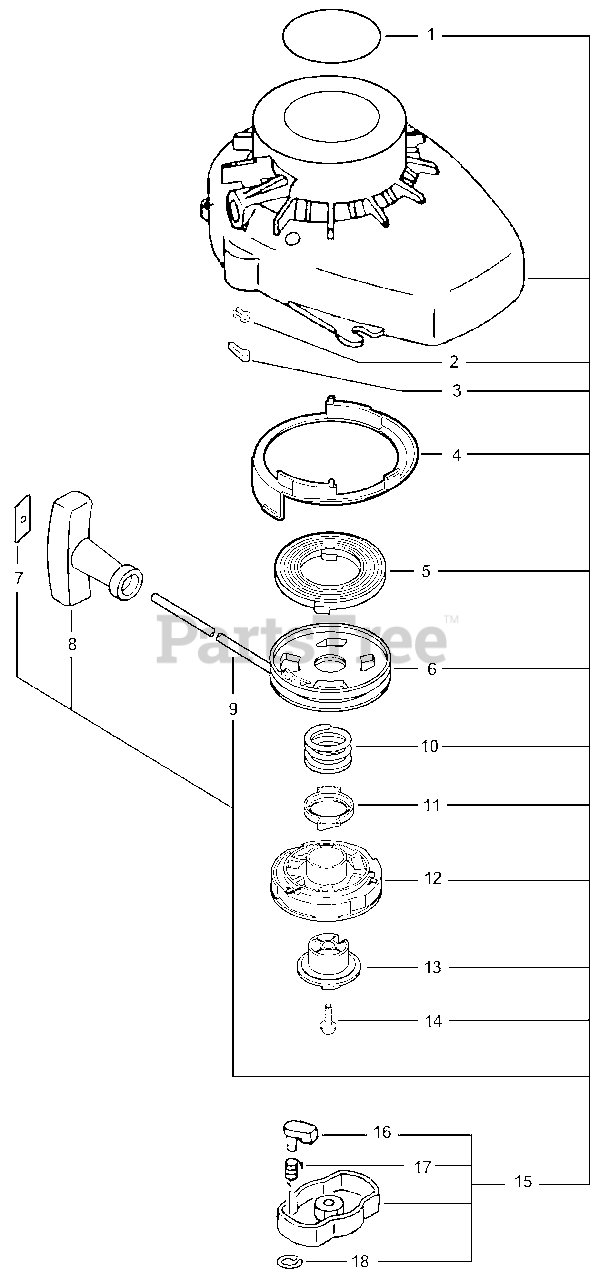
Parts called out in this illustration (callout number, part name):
1	LABEL
2	SPRING, PAWL RETURN
3	PAWL, STARTER
4	CASE, STARTER
5	SPRING, REWIND
6	REEL, ROPE
7	ROPE, STARTER - 3X800
8	GRIP, STARTER
9	RETAINER, ROPE
10	SPRING, RETURN
12	SPRING ASSY
13	PLATE, CAM
15	STARTER PAWL ASSY
16	PAWL, STARTER
17	SPRING, RETURN
18	RING, RETAINING - 4
